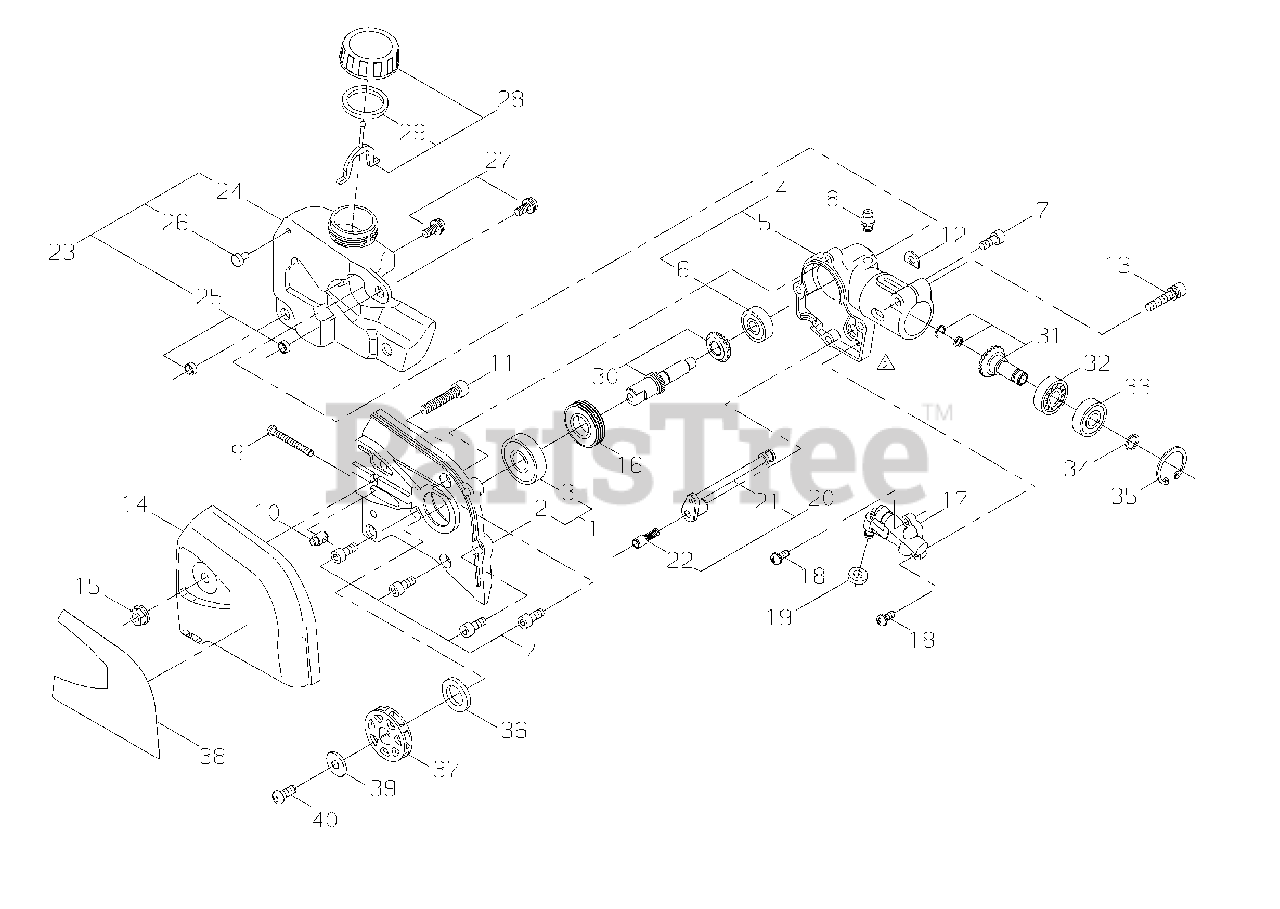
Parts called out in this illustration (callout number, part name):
1	COVER, GEAR CASE
2	COVER, GEAR CASE
3	BEARING, BALL 6001 DDU
4	GEAR CASE HOUSING ASSY
5	GEAR CASE HOUSING ASSY
6	BEARING, BALL 627ZZ
7	BOLT 5×12
8	FITTING, GREASE
9	SCREW - 4×35
10	TENSIONER, CHAIN
11	BOLT 4×10
12	D-WASHER
13	BOLT M5×25
14	COVER, SPROCKET
15	NUT, FLANGE M6
16	GEAR, WORM
17	OIL PUMP ASSY
18	SCREW
19	GASKET, AUTO-OILER
20	PIPE ASSY, OIL
21	PIPE, OIL
22	FILTER, OIL
23	TANK ASSY, OIL
24	TANK, OIL
26	VENT ASSY
27	SCREW M5×12
28	CAP ASSY, OIL
29	GASKET, CAP
30	GEAR SET, BEVEL
31	PINION, BEVEL
32	BEARING, BALL 609
33	BEARING, BALL 609ZZ
34	RING, SNAP
35	RING, SNAP Ø24
36	COLLAR 12
37	SPROCKET, DRIVE
38	LABEL, CAUTION
39	WASHER M6
40	SCREW, BUTTON
